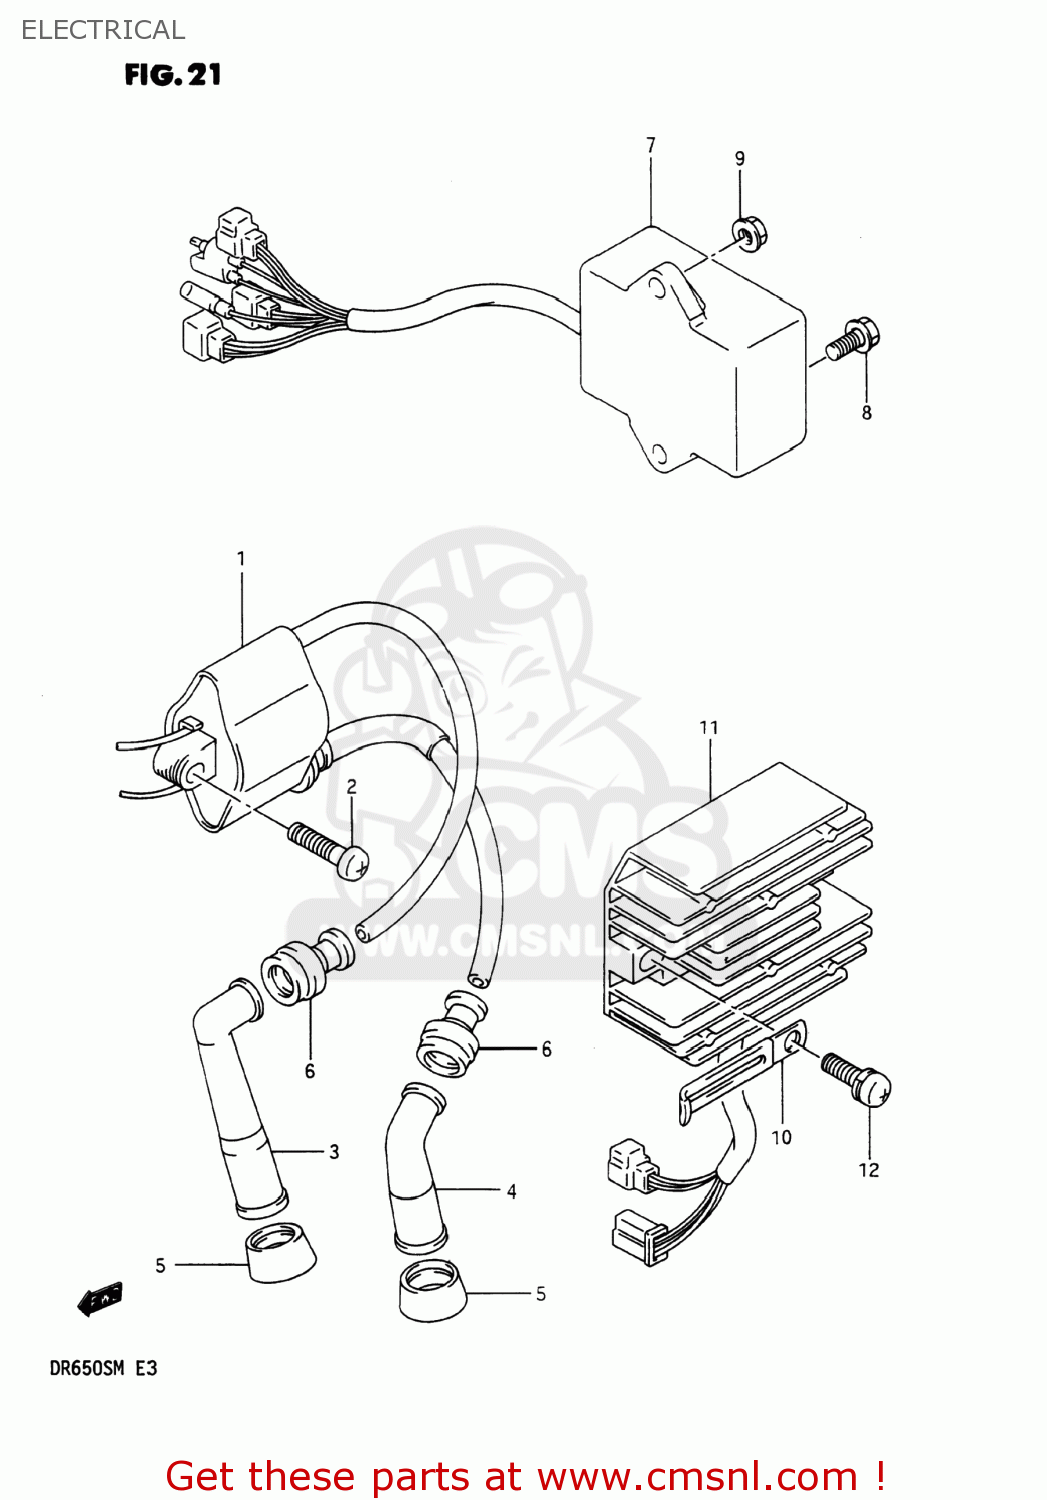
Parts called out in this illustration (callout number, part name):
1	COIL ASSY,IGNITION
2	SCREW
3	CAP ASSY,SPARK PLUG
4	CAP,SPARK PLUG
5	SEAL,SPARK PLUG CAP
6	SEAL,HIGH TENSION CORD
7	CDI UNIT
8	SCREW (6X16) WITH WASHER
9	NUT
10	CLAMP
11	RECTIFIER ASSY
12	SCREW
